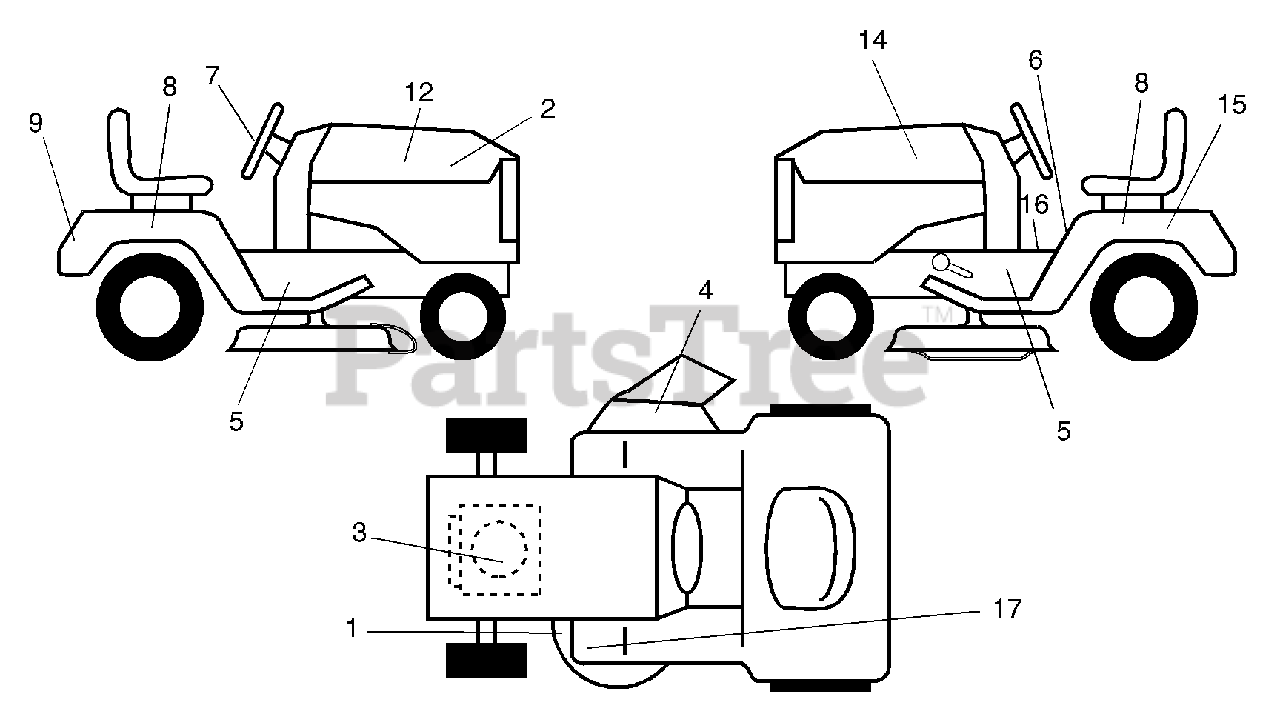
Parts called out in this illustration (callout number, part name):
1	Decal, Clutch/Brake
2	Decal, Replacement
3	Decal, Engine HP
4	Decal Deck "B" "42"
5	Decal, Chassis Statesman
5	Decal, Chassis Agway
6	Decal, Fender Danger
7	Decal, Steering Statesman
7	Decal, Steering Agway
8	Decal, Fender 5 Sp.
9	Decal, Fender Statesman
9	Decal, Fender Agway
12	Decal, Hood RH Statesman
12	Decal, Hood RH Agway
14	Decal, Hood LH Statesman
14	Decal, Hood LH Agway
15	Decal, Caution, Battery
16	Decal, Oper Sdl P/L Gear Dr Eng
17	Decal, V-Belt Sch.
